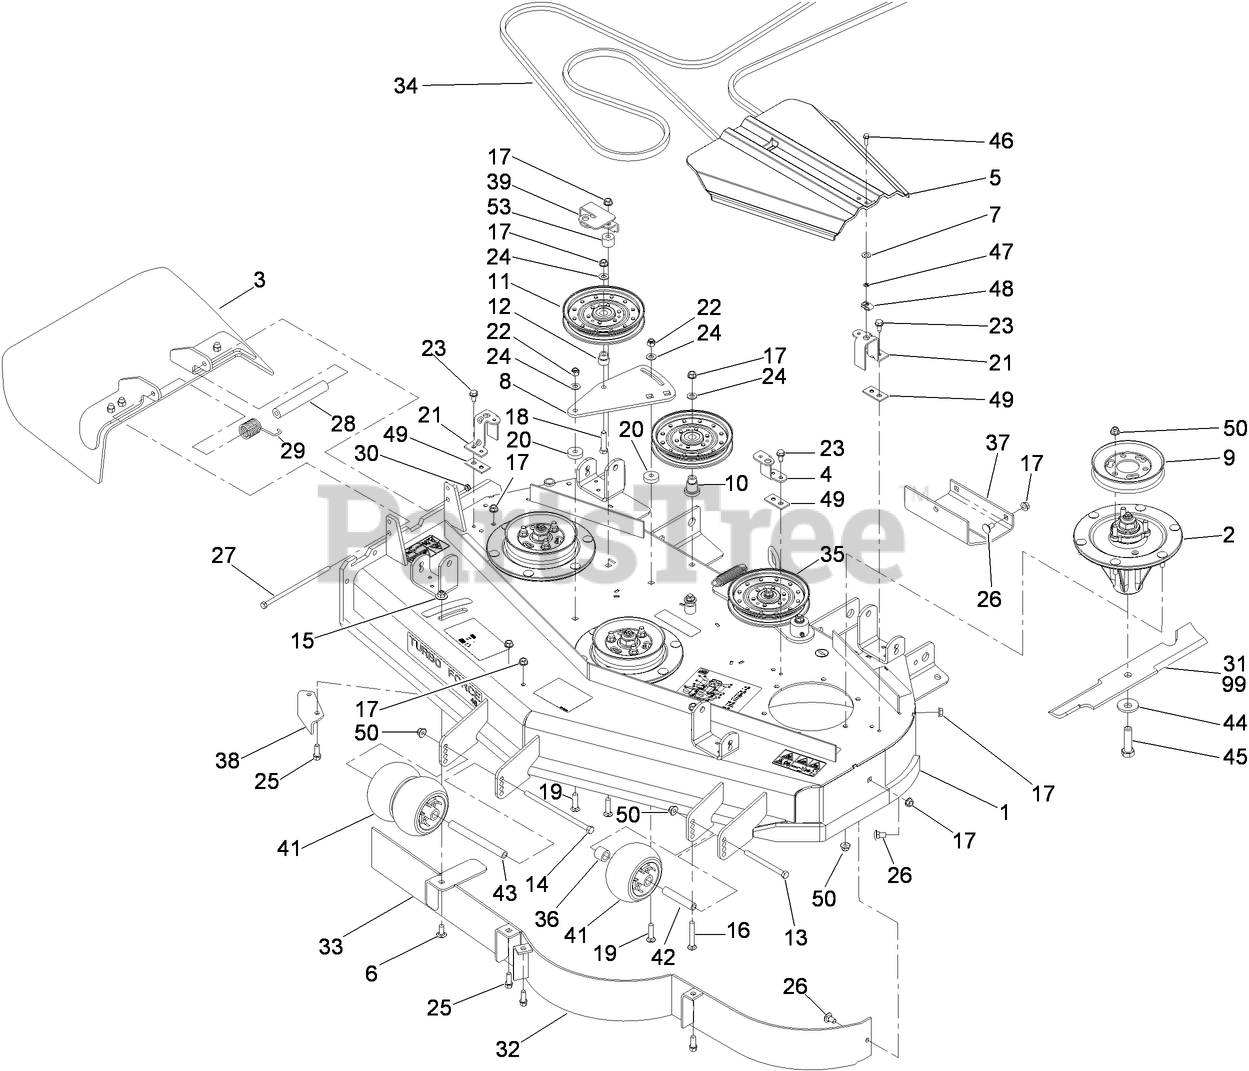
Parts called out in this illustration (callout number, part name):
1	DECK ASM
2	SPINDLE ASM
3	RUBBER DEFLECTOR ASM
4	BRACKET-COVER, TALL
5	COVER-BELT
6	SCREW-CARR
7	WASHER-THRUST
8	PLATE - IDLER
9	PULLEY
10	MOUNT-PULLEY
11	Idler-Flat
12	BUSHING-IDLER
13	SCREW-HH
14	SCREW-HH
15	NUT-FLANGE, NI
16	SCREW-CARR
17	NUT-HHF, WHIZ
18	SCREW-HH
19	SCREW-CARR
20	Spacer
21	BRACKET-COVER
22	NUT-LOCK, NI
23	SCREW-HWHTF
24	WASHER-FLAT
25	SCREW-HWH
26	SCREW-CARR
27	SCREW-HH
28	SPACER
29	SPRING-TORSION
30	NUT-LOCK, NI
31	BLADE-16.5 INCH (HIGH FLOW)
32	BAFFLE ASM
33	BAFFLE ASM
34	BELT-V
35	SPRING IDLER ASM
36	TUBE-SPACER
38	BAFFLE-DISCHARGE
39	BRACKET - COVER
41	ROLLER-SCALP, ANTI
42	TUBE-SPANNER
43	SPACER-WHEEL
44	Washer-Blade Bolt, Heavy
45	SCREW-BLADE
46	SCREW-HWH
47	NUT-RETAINER
49	SPACER-COVER, BELT
50	NUT-HF, NI
53	SPACER
99	BLADE-ROTARY, 16.5 INCH (MED FLOW)
99	BLADE-ROTARY, 16.5 INCH (ATOMIC)
99	BLADE-RECYCLER, 16.5 INCH
99	BLADE-ROTARY, 16.5 INCH (LOW FLOW)
